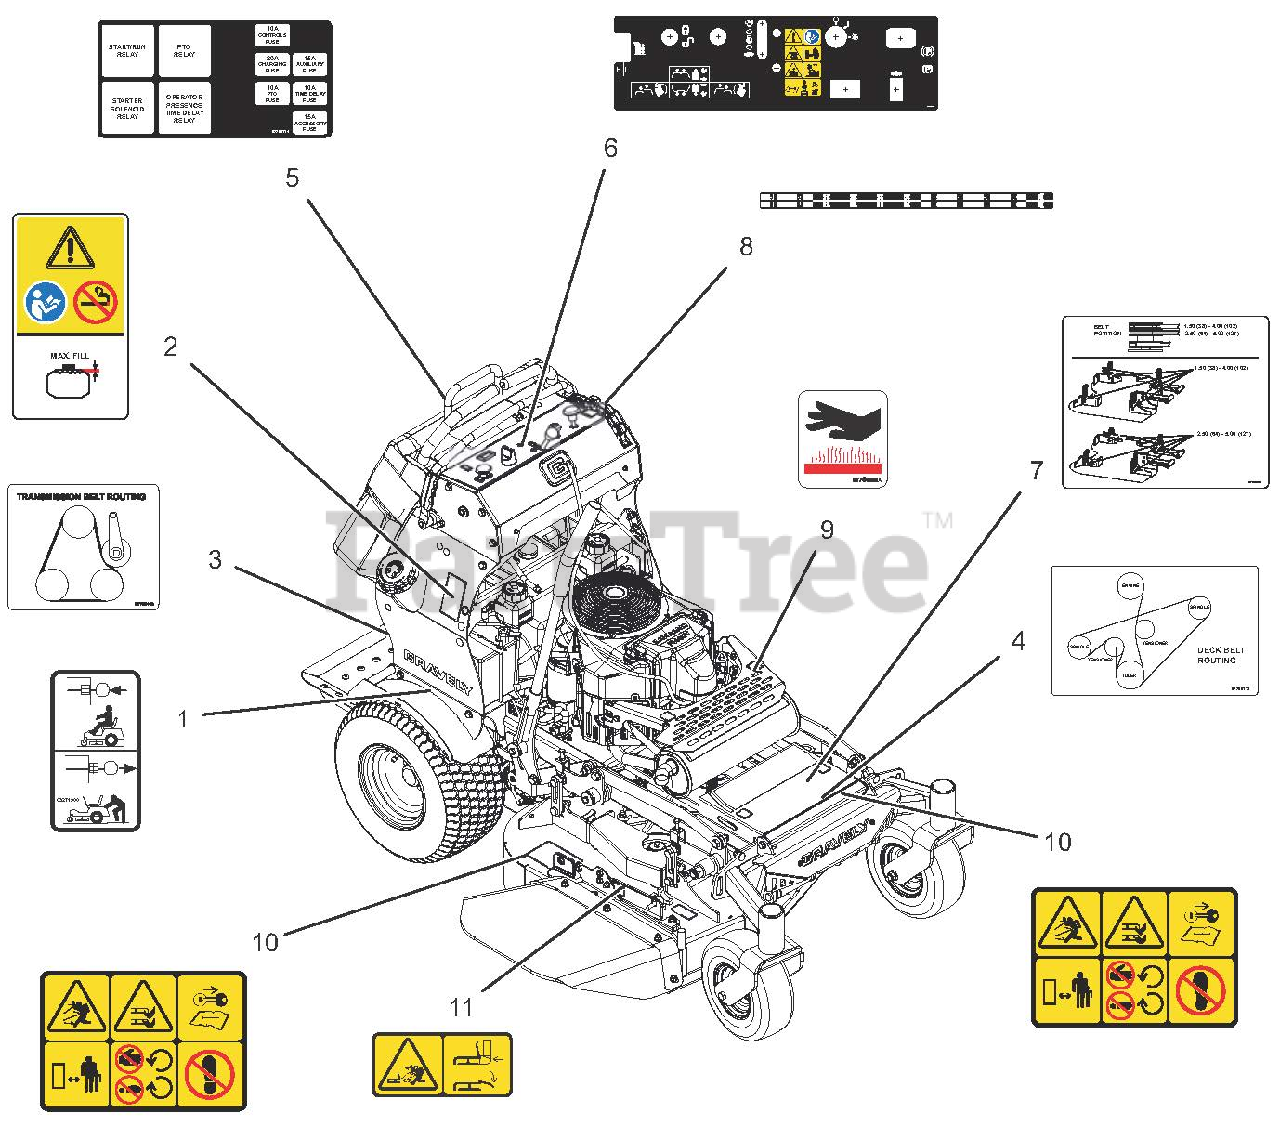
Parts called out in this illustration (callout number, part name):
1	DECAL, TRANSMISSION DISCONNECT
2	DECAL, FUEL WARNING
3	DECAL, HYDRO BELT 36 PROSTANCE
4	DECAL, BELT RTG 36 PROSTANCE
5	DECAL, FUSE BLOCK
6	DECAL, 36 PS CONTROL PANEL
7	DECAL, BELT POSITIONING
8	DECAL, 36 PS HOC DIAL
9	DECAL, HOT SURFACE
10	DECAL, SAFETY - MOWER DECK
11	DECAL, SAFETY - DECK GUARDING
